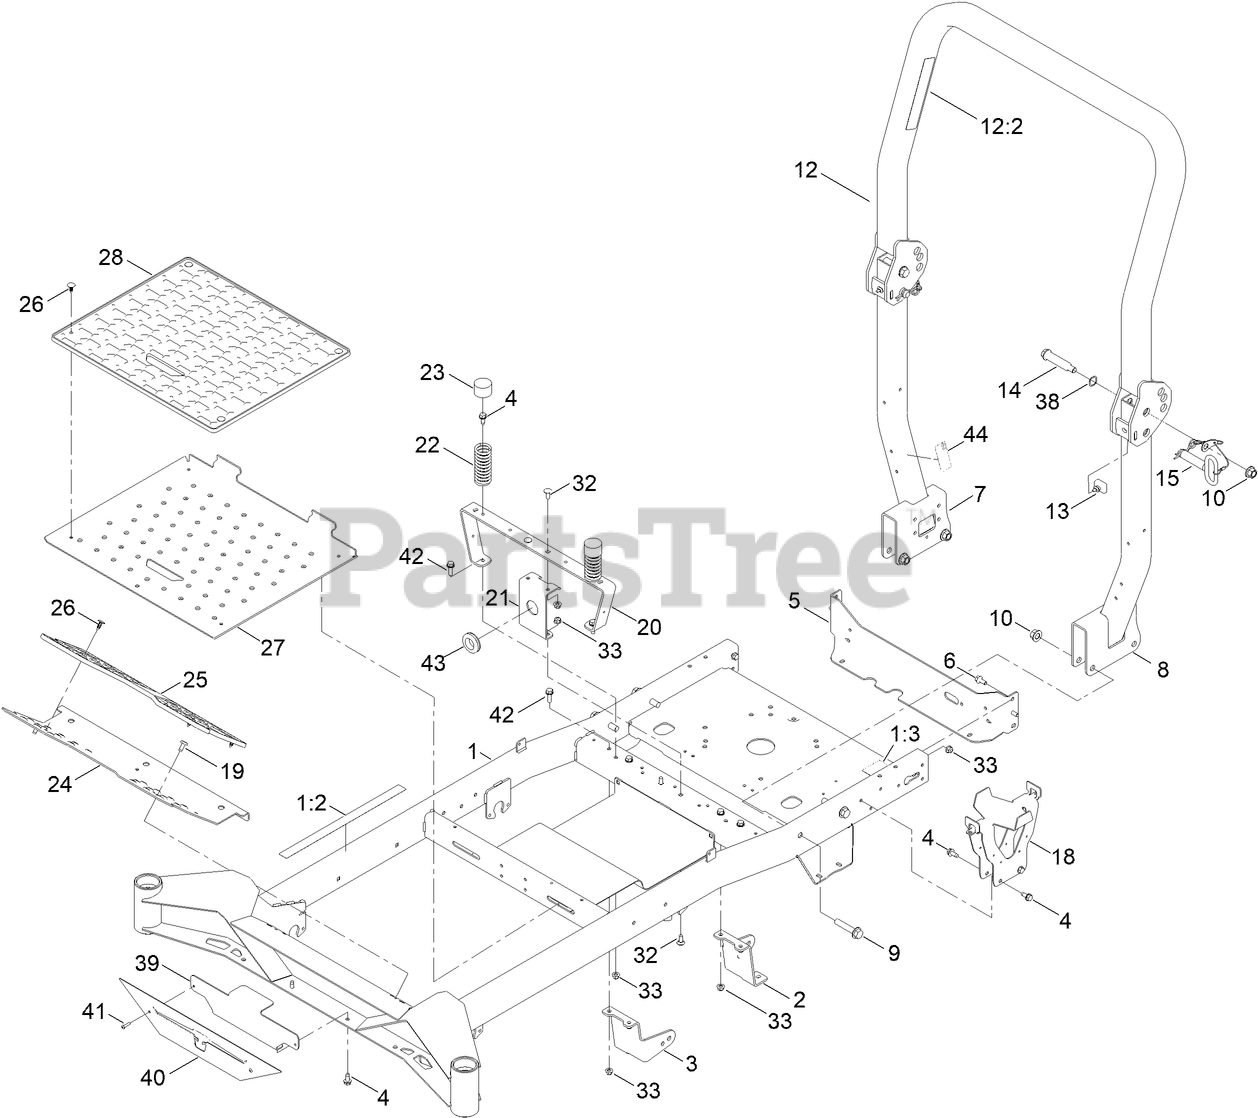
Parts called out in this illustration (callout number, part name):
1	FRAME W/DECALS ASM
1:2	DECAL-WARNING
1:3	DECAL-BYPASS
2	MOUNT-DRIVE, LH
3	MOUNT-DRIVE, RH
4	SCREW-HWHTF
5	PLATE-MOUNT, REAR
6	SCREW-HHF
7	RH ROPS ASM [BLACK]
8	LH ROPS ASM [BLACK]
9	SCREW-HHF
10	NUT-HF
12	TUBE-ROPS, UPPER ASM
12:2	DECAL-WARNING
13	BUMPER-ROPS
14	BOLT-SHOULDER
15	PIN-ROPS, ASM
18	TRAY-BATTERY
20	SUPPORT-SEAT
21	BRACKET-LATCH, FRAME (MTY/BTV)
22	SPRING-COMPRESSION
23	CAP-PROTECTOR
24	PAN-FLOOR
25	FLOOR MAT - TITAN
26	PLUG-PLASTIC
27	PAN-FLOOR
28	FLOOR MAT
32	SCREW-CARR
33	NUT-HF, NI
38	WASHER-WAVE
39	PLATE-BACKER
40	LOGO-PLATE-FRONT
41	RIVET-TRIFOLD
42	SCREW-HHF
43	GROMMET
44	DECAL-COMPLIANCE, ROPS
